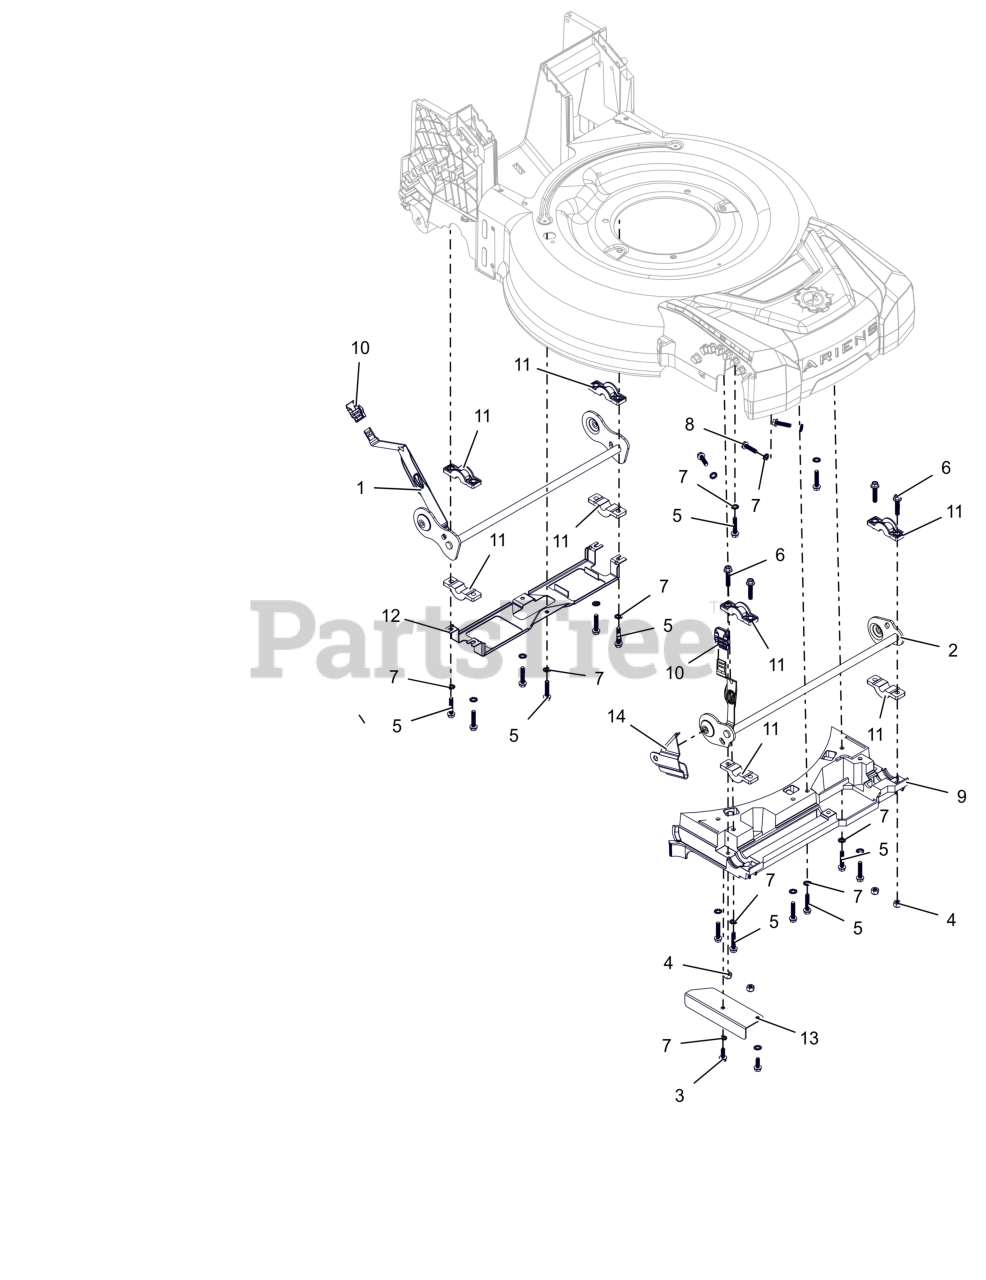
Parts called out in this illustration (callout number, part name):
1	WLDMT, REAR AXLE - PUSH (BLACK)
2	WLDMT, FRONT AXLE - PUSH (BLACK)
3	SCR, HI-LO HWH 1/4-15 X .750
4	NUT, NYLOC 1/4-20
5	SCR, HI-LO HWH 1/4-15 X 1.25
6	BLT, HWH 1/4-20 X 1.25
7	WSHR-LK-EXT, .256X.510X.028
8	SCR, HI-LO HWH 1/4-15 X 1.00
9	TRAY, FRONT
10	GRIP, HOC
11	BUSHING, SHAFT - HOC
12	BRKT, RWD BACK SUPPORT (BLACK)
13	FLANGE, BLOW OUT (BLACK)
14	BRKT, ARM SUPPORT (BLACK)
